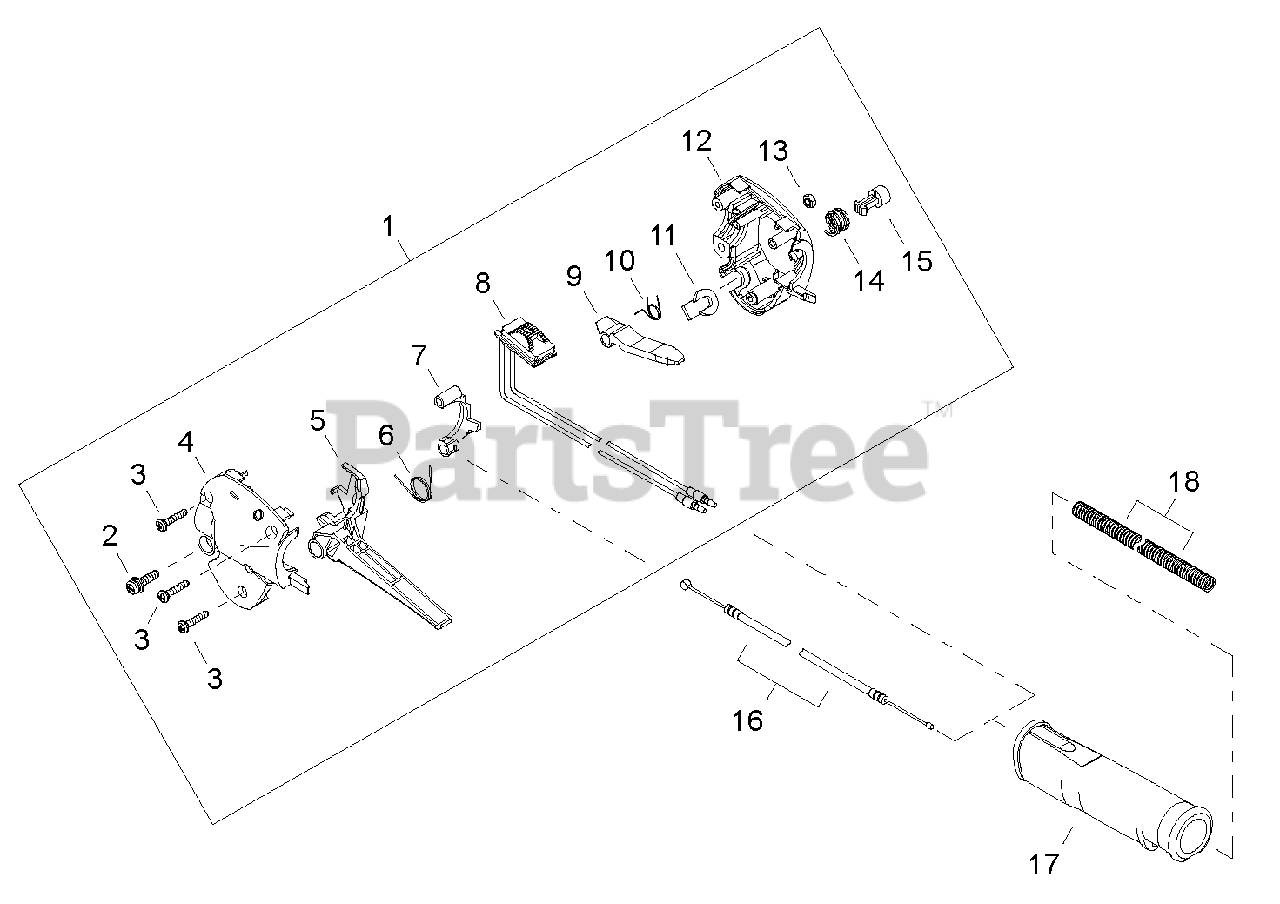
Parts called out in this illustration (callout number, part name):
1	CONTROL HANDLE ASSY
2	SCREW - 5X20
3	SCREW - 4X20 -- TAPPING
4	HANDLE, CONTROL - LEFT
5	TRIGGER, THROTTLE
6	SPRING
7	LOCKOUT, THROTTLE
8	SWITCH, IGNITION
9	LEVER, TRIGGER LOCKOUT
10	SPRING
11	PLUG
12	HANDLE, CONTROL - RIGHT
13	NUT - 5
14	SPRING
15	BUTTON, THROTTLE LOCK
16	CABLE, THROTTLE
17	GRIP, THROTTLE CONTROL
